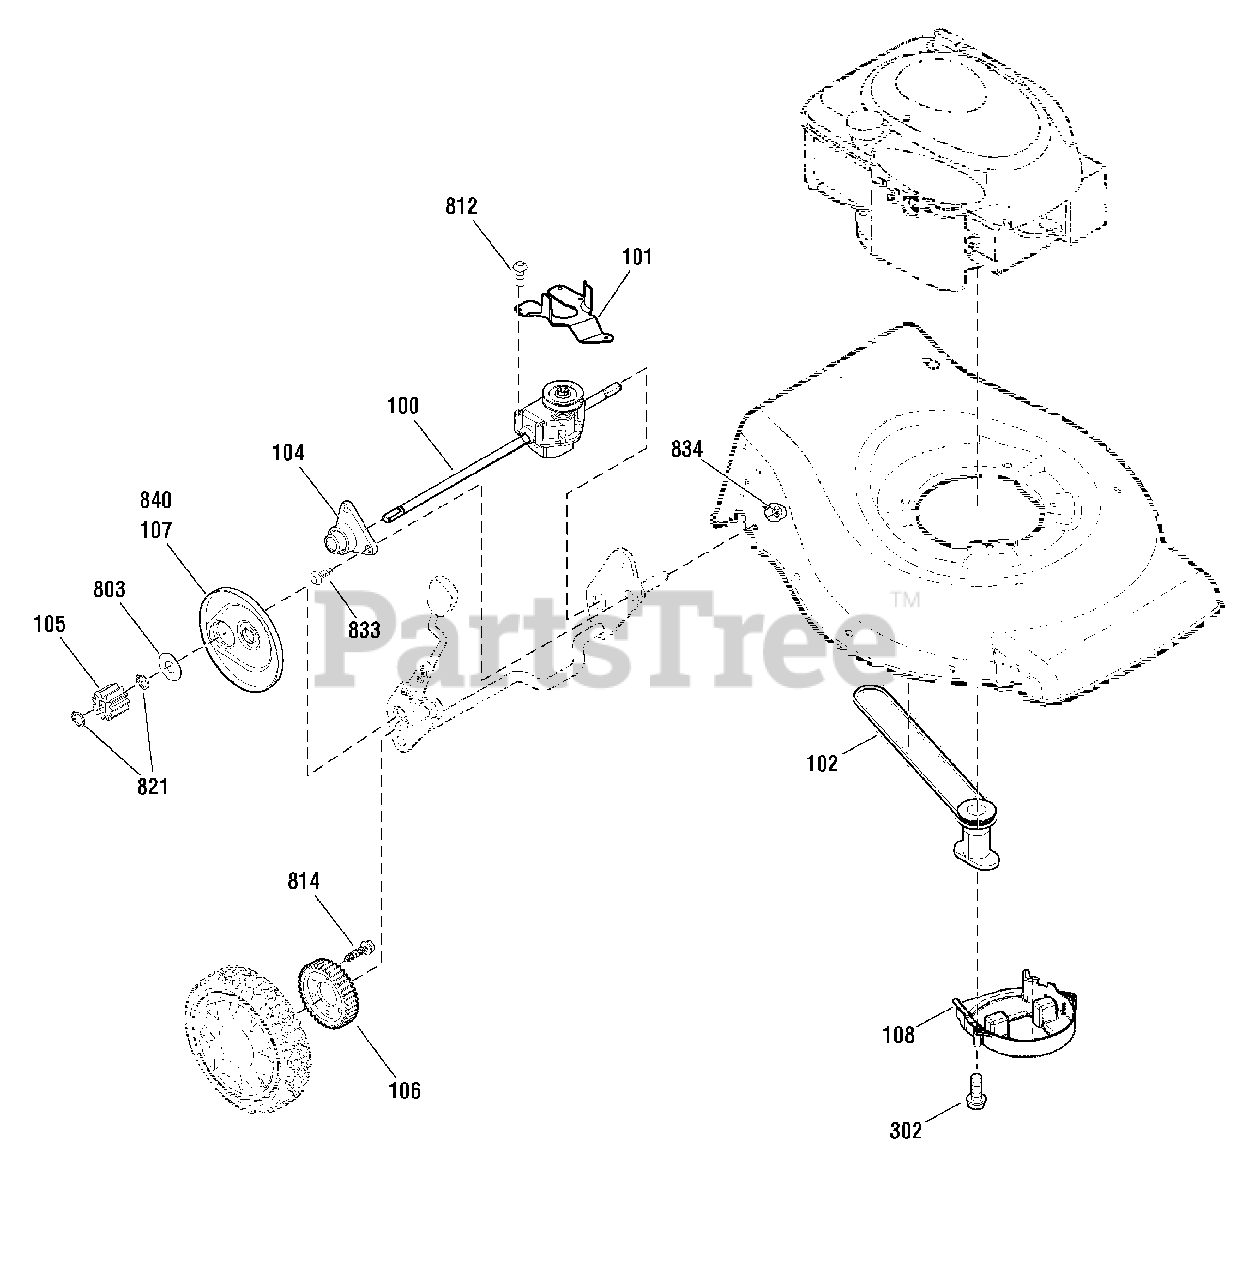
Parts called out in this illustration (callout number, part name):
100	TRANSMISSION
101	BELT GUIDE, Transmission
102	V-BELT
104	SLEEVE ASSEMBLY, Rear Axle
105	GEAR, Pinion
106	GEAR, Drive
107	DUST COVER, LH
108	BELT COVER ASSEMBLY
302	SCREW, Pan Head Torx, 1/4-20 x 1/2
803	WASHER, Thrust
812	SCREW, #10 x 1
814	SCREW, 1/4-15 x 3/4
821	RING, External Retaining
833	SCREW, Torx, 1/4-20 x 5/8
834	NUT, Flange Lock, 1/4-20
840	DUST COVER, RH
